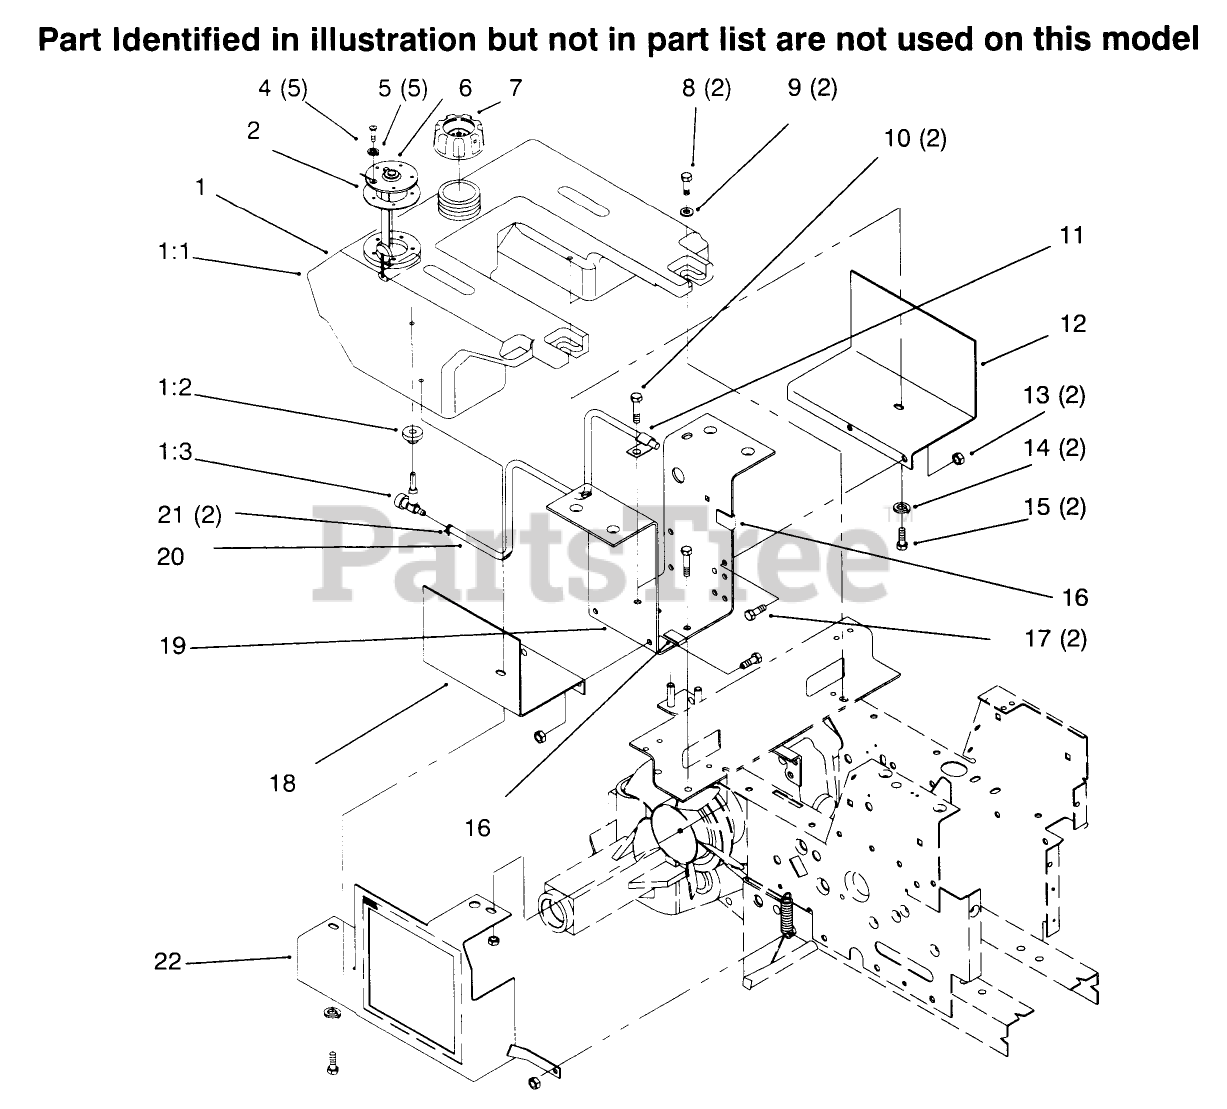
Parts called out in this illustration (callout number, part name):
1	TANK-FUEL
7	GAS CAP ASM
8	SCREW-HWHTF
9	WASHER-FLAT
10	SCREW-HH, LOCK
11	CLIP
12	Fuel Tank Support LH
13	NUT-LOCK, NI
14	WASHER-LOCK
15	SCREW-HH
16	CLIP-CABLE
17	SCREW-HH
18	Support-FueITank RH
19	Bracket-Fender
20	Line-Fuel 62"
21	CLAMP-HOSE
